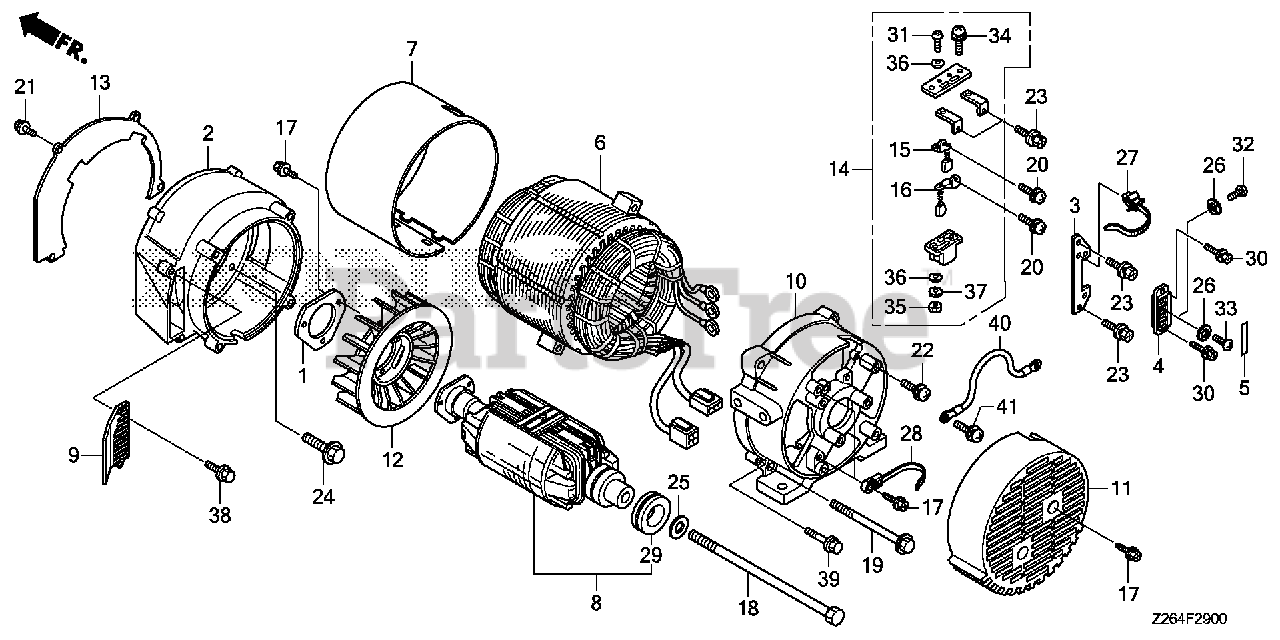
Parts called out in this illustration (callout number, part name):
1	PLATE, COOLING FAN
2	HOUSING, FR.
3	BRACKET, A.C. OUT TERMINAL
4	TERMINAL, A.C. OUT
6	STATOR ASSY.
7	COVER, BAND
9	DUCT, GENERATOR
10	HOUSING, RR.
11	COVER, GENERATOR END
12	FAN, GENERATOR COOLING
13	BRACKET, FR.
14	BRUSH ASSY.
17	SCREW, TAPPING (5X14)
18	BOLT, HEX. (10X278)
19	BOLT, FLANGE (8X170)
20	SCREW-WASHER (4X8)
21	BOLT, FLANGE (5X12)
22	SCREW-WASHER (6X12)
23	BOLT-WASHER (6X15)
24	BOLT, HEX. (3/8-16UNCX25)
25	WASHER (10.5MM)
26	WASHER, SPRING (6MM)
27	STRAP, CABLE (118MM) (BLACK)
28	TIE, CABLE
29	BEARING ASSY. (6306NCX)
30	BOLT-WASHER (5X20)
31	SCREW, PAN (4X16)
32	SCREW, PAN (6X8)
33	SCREW, PAN (6X12)
34	SCREW-WASHER (5X10) (NOT AVAILABLE)
35	NUT, HEX. (4MM) (NOT AVAILABLE)
36	WASHER, PLAIN (4MM)
37	WASHER, SPRING (4MM)
38	BOLT, FLANGE (6X12)
39	BOLT, FLANGE (6X45)
40	WIRE, GROUND
41	SCREW-WASHER (6X12)
